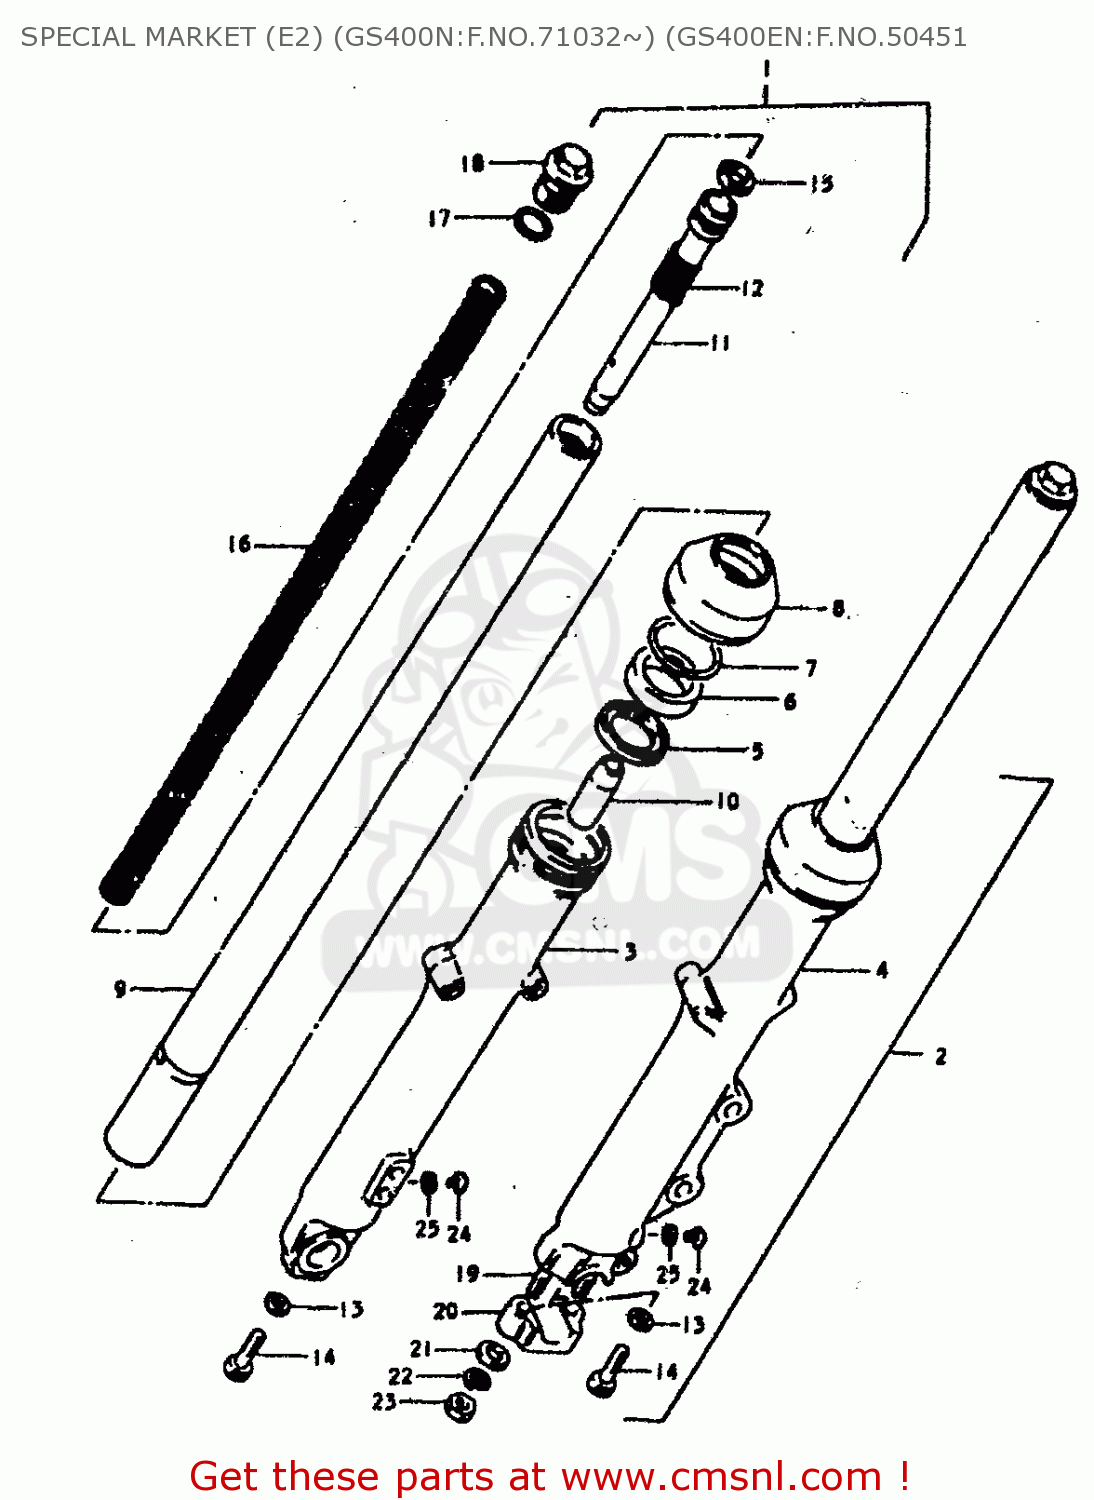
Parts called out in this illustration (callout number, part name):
1	DUMPER ASSY,RH
2	DUMPER ASSY, FRONT FORM LH
3	TUBE,FORK,OUTER,RIGHT
4	TUBE,FORK,LEFT,OUTER
5	SPACER,OIL SEAL
6	OIL SEAL,FRONT FORK
7	CIRCLIP,FORK OIL SEAL
8	BOOT
9	TUBE,INNER
10	PIECE,OIL LOCK
11	CYLINDER,FRONT FORK
12	SPRING,REBOUND
13	GASKET (NAS)
14	BOLT(8X27)
15	RING,PISTON
16	SPRING
17	O RING
18	BOLT
19	STUD 8X25
20	HOLDER,AXLE
21	WASHER
22	LOCK WASHER
23	NUT (8MM)
24	SCREW 4X6
25	GASKET (NAS)
